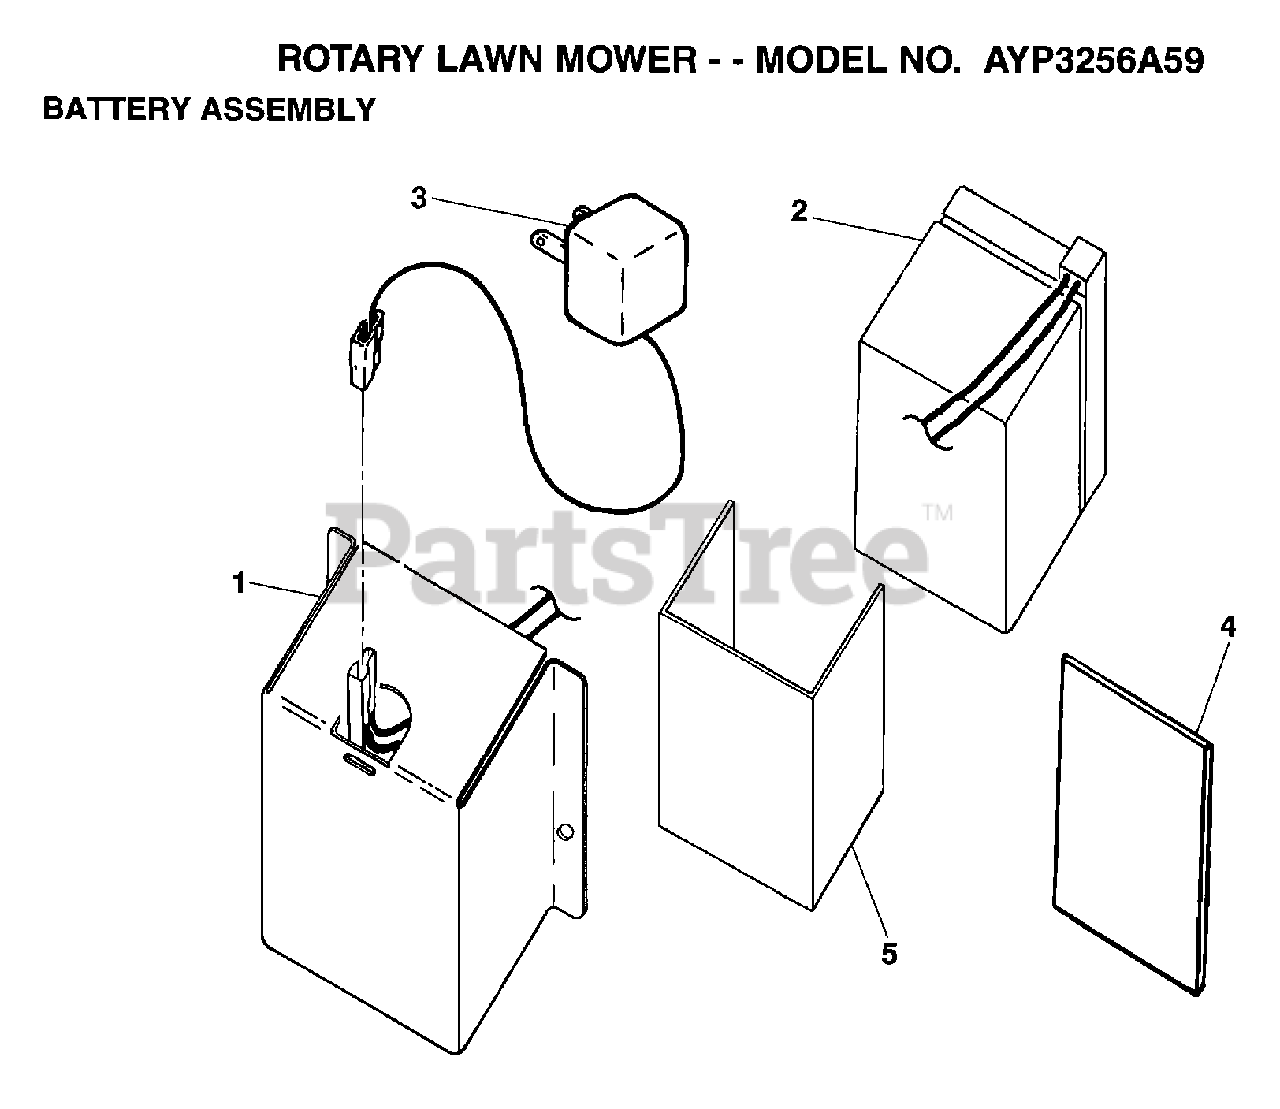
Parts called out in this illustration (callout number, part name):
1	BRACKET BATR'Y
3	CHARGER PM
4	"PAD PM, BATTERY"
5	"WRAP, BATTERY"
